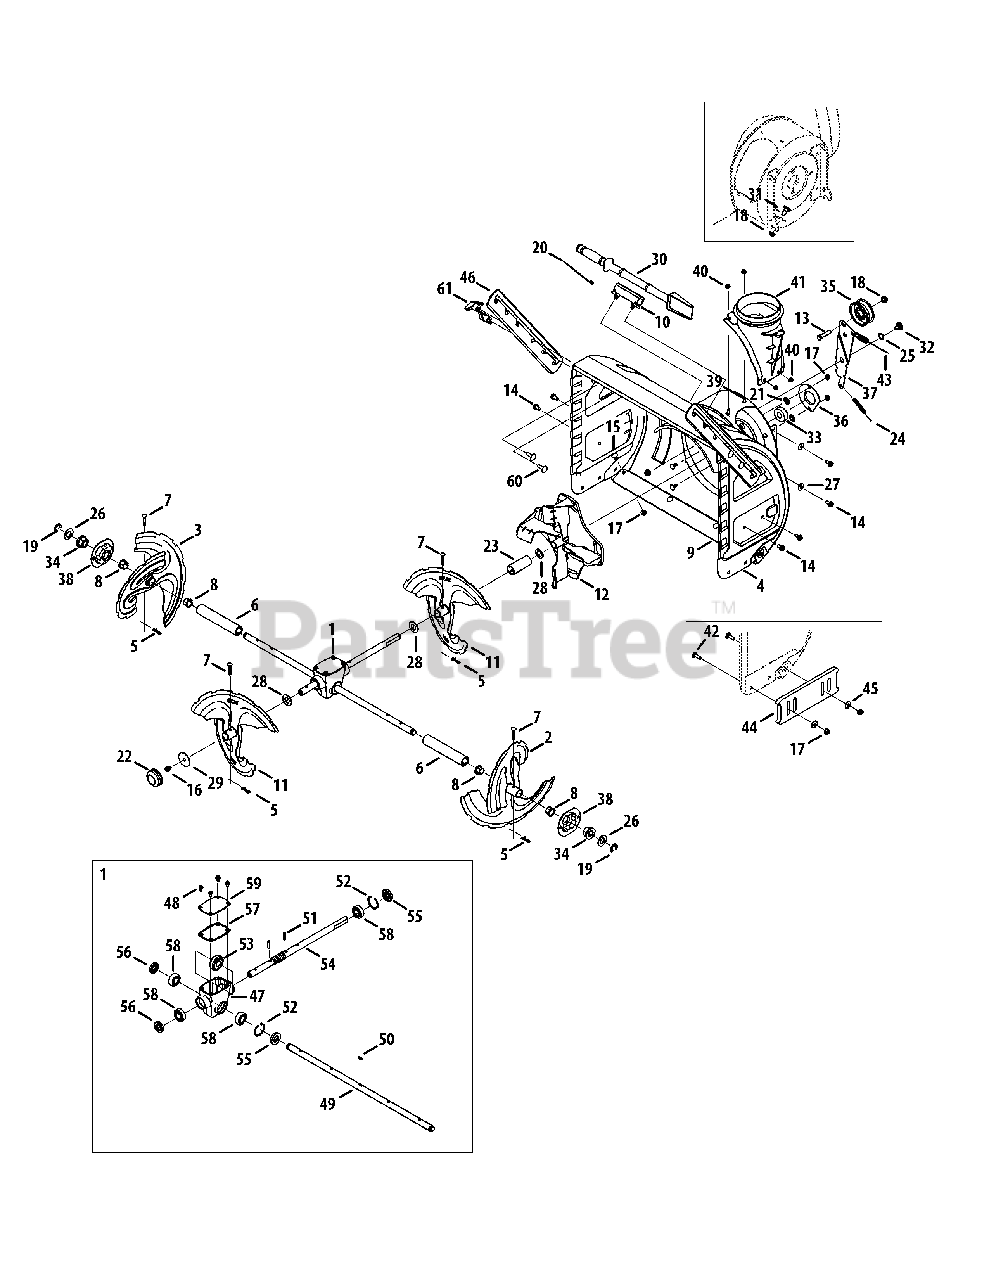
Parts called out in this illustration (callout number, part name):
1	Gearbox Assembly, Auger, 28"
2	Spiral Assembly - LH, 26" & 28"
3	Spiral Assembly - RH, 26" & 28"
4	Auger Housing, 28"
5	Bow Tie Cotter Pin
6	Spacer, 1.25 OD x .75 ID x 7.805 (28")
8	Flange Bushing, .800 x .910
9	Shave Plate, 28"
10	Clean-out Tool Mtg. Bracket
11	Accelerator Assembly
12	Impeller Assembly
13	Hex Bolt, 3/8-16 x 1.75
14	Screw, 5/16-18 x .750
15	Carriage Bolt, 5/16-18 x .750
16	Hex Washer Screw, 5/16-18 x .500
17	Flange Lock Nut, 5/16-18
18	Flange Lock Nut, 3/8-16
19	E-ring, .75
20	Cable Tie
21	Push-On Nut, .25 Dia.
23	Spacer, 1.35 OD x .76 ID x 2.755
24	Extension Spring, .38 OD x 4.59
25	Wave Washer, .625 x .885 x .0175
26	Flat Washer, .76 x 1.49 x .06
27	Bell Washer, .340 x .872 x .060
28	Flat Washer, .793 x 1.24 x .06
29	Flat Washer, .406 x 1.92 x .060
30	Clean-Out Tool
31	Shoulder Screw, 3/8-16 x .496 x .336
32	Shoulder Screw, 3/8-16 x .625 x .17
33	Flange Ball Bearing, .75 x 1.85
34	Hex Flange Bearing, .75 ID
35	Flat Idler Pulley
36	Bearing Housing
38	Bearing Housing
39	Carriage Screw, 1/4-20 x 0.75
40	Flange Lock Nut, 1/4-20
41	Chute Adapter
42	Spacer, Carriage, 5/16-18 x 1.00
43	Auger Clutch Cable
44	Deluxe Slide Shoe
45	Washer, Flat, .349 x .879 x .063
47	Auger Housing
48	Screw, 1/4-20 x 0.75
49	Axle, Auger, 28"
50	Hi-Pro Key
51	Pin, Roll, .25 x 1.0
52	Retainer Ring
53	Worm Gear, 20T
54	Worm Shaft
55	Seal, .75 x 40mm x .25
56	Seal, .75 x 1.375 x .25
57	Gearbox Gasket
58	Ball Bearing, .75 x 40 x 12
59	Gearbox Cover
60	Carriage Bolt, 5/16-18 x .875
61	Wing Knob, 5/16-18
